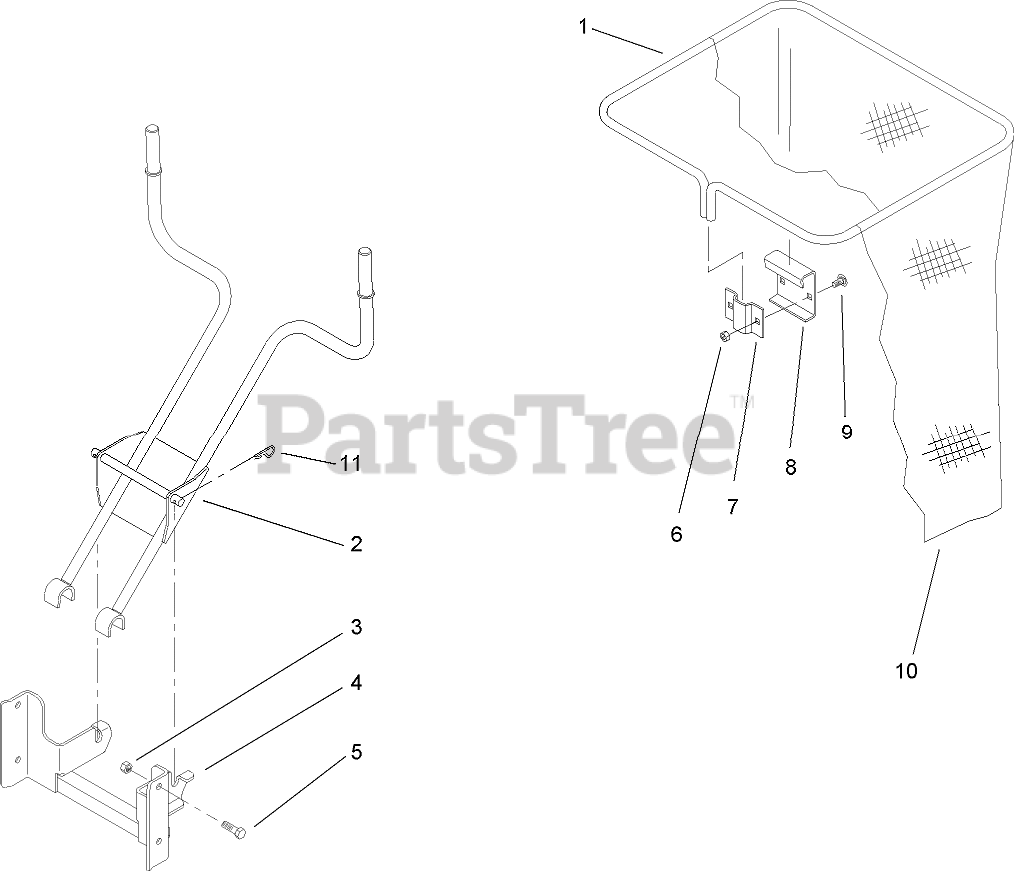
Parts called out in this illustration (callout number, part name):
1	FRAME-BAG
2	BRACKET-ATTACH, QUICK
3	NUT-LOCK, NI
4	SUPPORT-BAGGER
5	SCREW-HH
6	NUT-LOCK, NI
8	HANGER-BAG
9	BOLT-CARR
10	BAG-DEPTH
11	PIN-COTTER, HAIR
